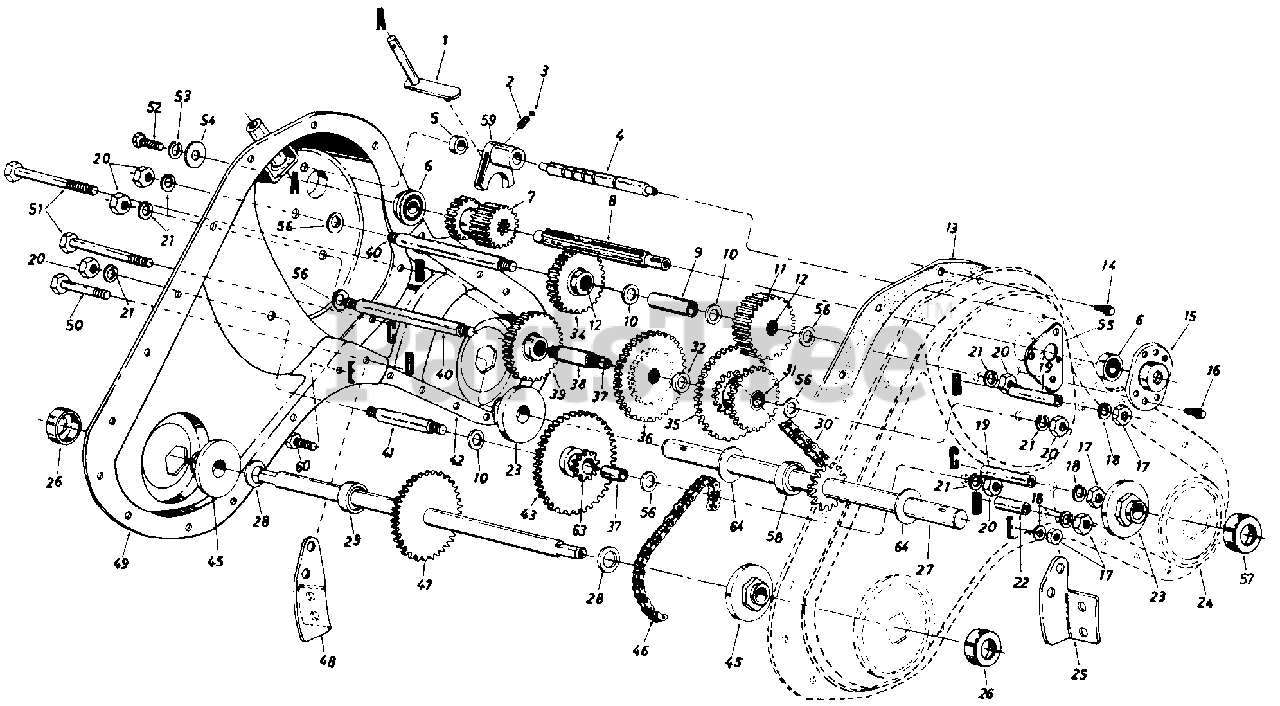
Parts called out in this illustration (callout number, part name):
1	Shifting Bracket Ass'y.
2	Compression Spring .60" Lg.
3	Ball Detent .50" Dia.
4	Detent Shaft 1/2" Dia.
5	Spacer .505" I.D. x .88" O.D.
6	Ball Brg. .62" I.D. x 1.38"
7	Spur Gear 16T (Input)
8	Input Spline Shaft 7/8"
9	Spacer .657" I.D. x 2.85" Lg.
10	Fl-Wash. .640" l.D. x 1.24"
11	Spur Gear 30T 7/8" l.D.
12	Needle Bearing 5/8" I.D.
13	Gasket-Trans. Hsg.
14	Hex Wash. S-Tap Scr. 1/4-20 x.50" Lg.
15	1-3/8" Dia. Bearing Housing
16	Hex TT-Tap Scr. 1/4-20 x .75"
17	Hex Nut 5/16-18 Thd.
18	L-Wash. 5/16" I.D.
19	Spacer 1.561' Lg.
20	Hex Nut 7/16-20 Thd.
21	Bell-Wash. .45" l.D. x 1.0n
22	Spacer 1.015" Lg.
23	Tine Shaft Brg. 1.002 x 2.50
24	Trans. Housing Ass'y.-L.H.
27	Tine Shaft Ass'y. l" O.D.
28	Fl-Wash. .75" l.D. x 1.5" O.D.
29	Spacer .75" l.D. x 50" Lg.
30	Chain #50 5/8 Pitch x 52 0 Links-Endless
31	Needle Bearing 518" I.D.
32	Fl-Wash. 5/8" l.D.
34	Spur Gear 30T 12/16" I.D.
35	30/44T Gear Ass'y. Comp.
36	Spur Gear 44T
37	Sleeve Bearing
38	Gear Hub 3/4" I.D. x 3" Lg.
39	Spur Gear 30T 1.0" I.D. x 1/2" W
40	Jack Shaft 5/8" Dia. x 5"
41	Jack Shaft 5/8" Dia. x 2.38"
42	Trans. Housing Ass'y.-R.H.
43	Spur Gear 55T
45	Wheel Brg. .752" x 2.5"
46	#420 Chain 1/2 Pitch x 50 0 Links-Endless
47	Wheel Shaft Ass'y. 15.6"
51	Hex Bolt 5/16-18 x 2.5"*
52	Hex Bolt 1/4-20 x .62" Lg.
53	L-Wash. 3/8" I.D.*
54	Fl-Wash. 1/4" I.D. x .93" O.D.
55	Gear Positioner Bracket
56	Fl-Wash. 7/16" I.D. x 1-3/8"
57	Dust Cover Ass'y. 1" Shaft
58	Spacer 1" I.D. x 2" O.D.
59	Shifting Fork
60	Hex Bolt 5/16-18 x .75" Lg.
63	10T Sprocket Ass'y.
64	Thrust Wash. 1.03" I.D. x 1.62" O.D.
